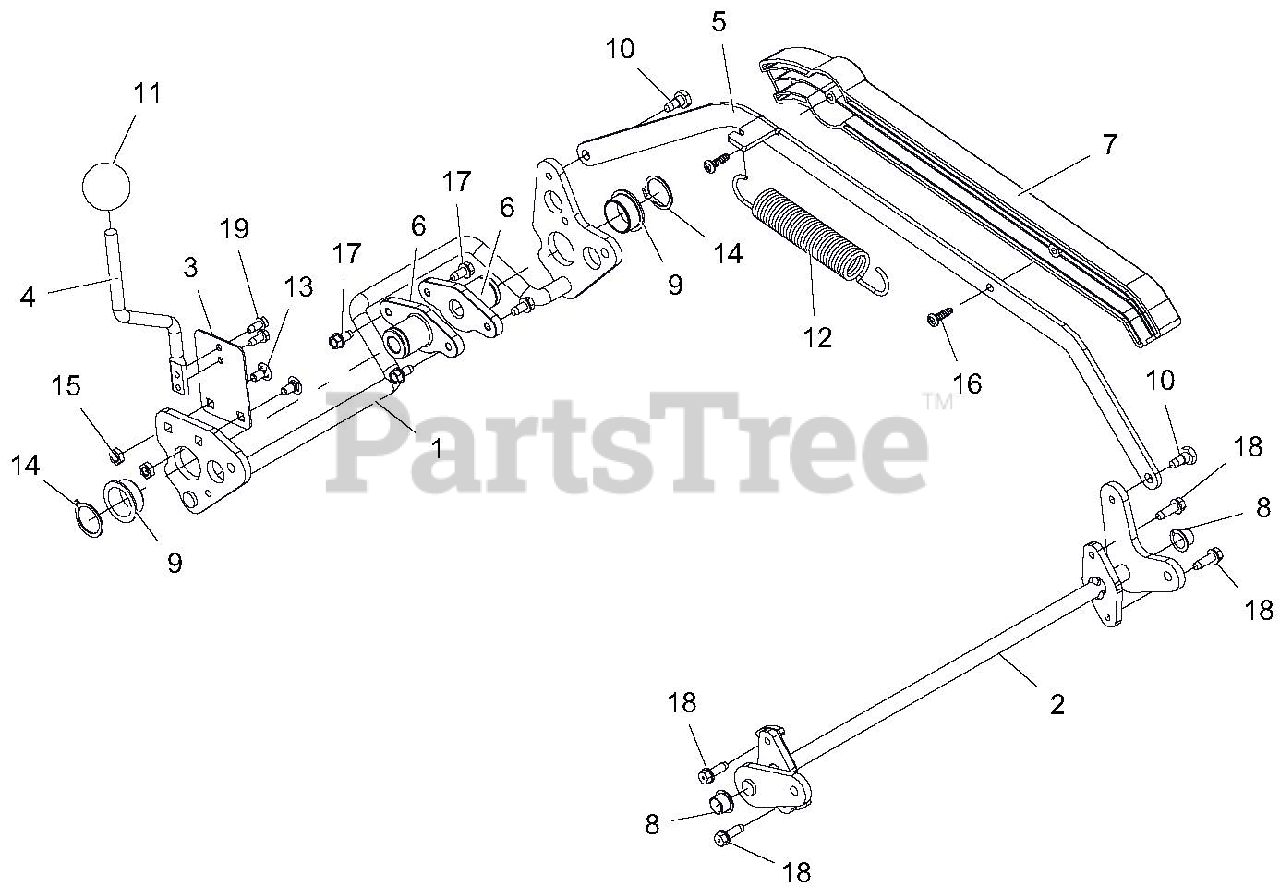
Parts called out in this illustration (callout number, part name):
1	WLDMT, REAR AXLE
2	WLDMT, LM FRONT AXLE
3	PLATE, HOC SPRING
4	LEVER, HOC ADJUST
5	LINK, HOC CONNECT
6	HUB, LM REAR AXLE
7	COVER, LINK ROD
8	BUSHING, POLYLINER - .50 SPLIT
9	BSHG, FLANGE 1.0x1.125x.50x1.375
10	BOLT, SHLDR .320X.210X.25-20 SELF-TAPPING
11	KNOB,BALL -BLACK 1.47" .375-16
12	SPRG, EXTENSION
13	BLT-RDHDSQNK .25-20X.50 G5 Y
14	RG-RTNG-EXT 1.00X.042
15	@NUT-LK-CTR-JAM .25-20 YWZC
16	SCR-TAP #12-14X.75 PLASTITE BLZC
17	SCR-TAP .25-20X.50 HWH TR YWZ
18	SCR-TAP .25-20X.75 HWH TR YWZ
19	SCR-TAP 12-24X.50 HWH TR YWZC
